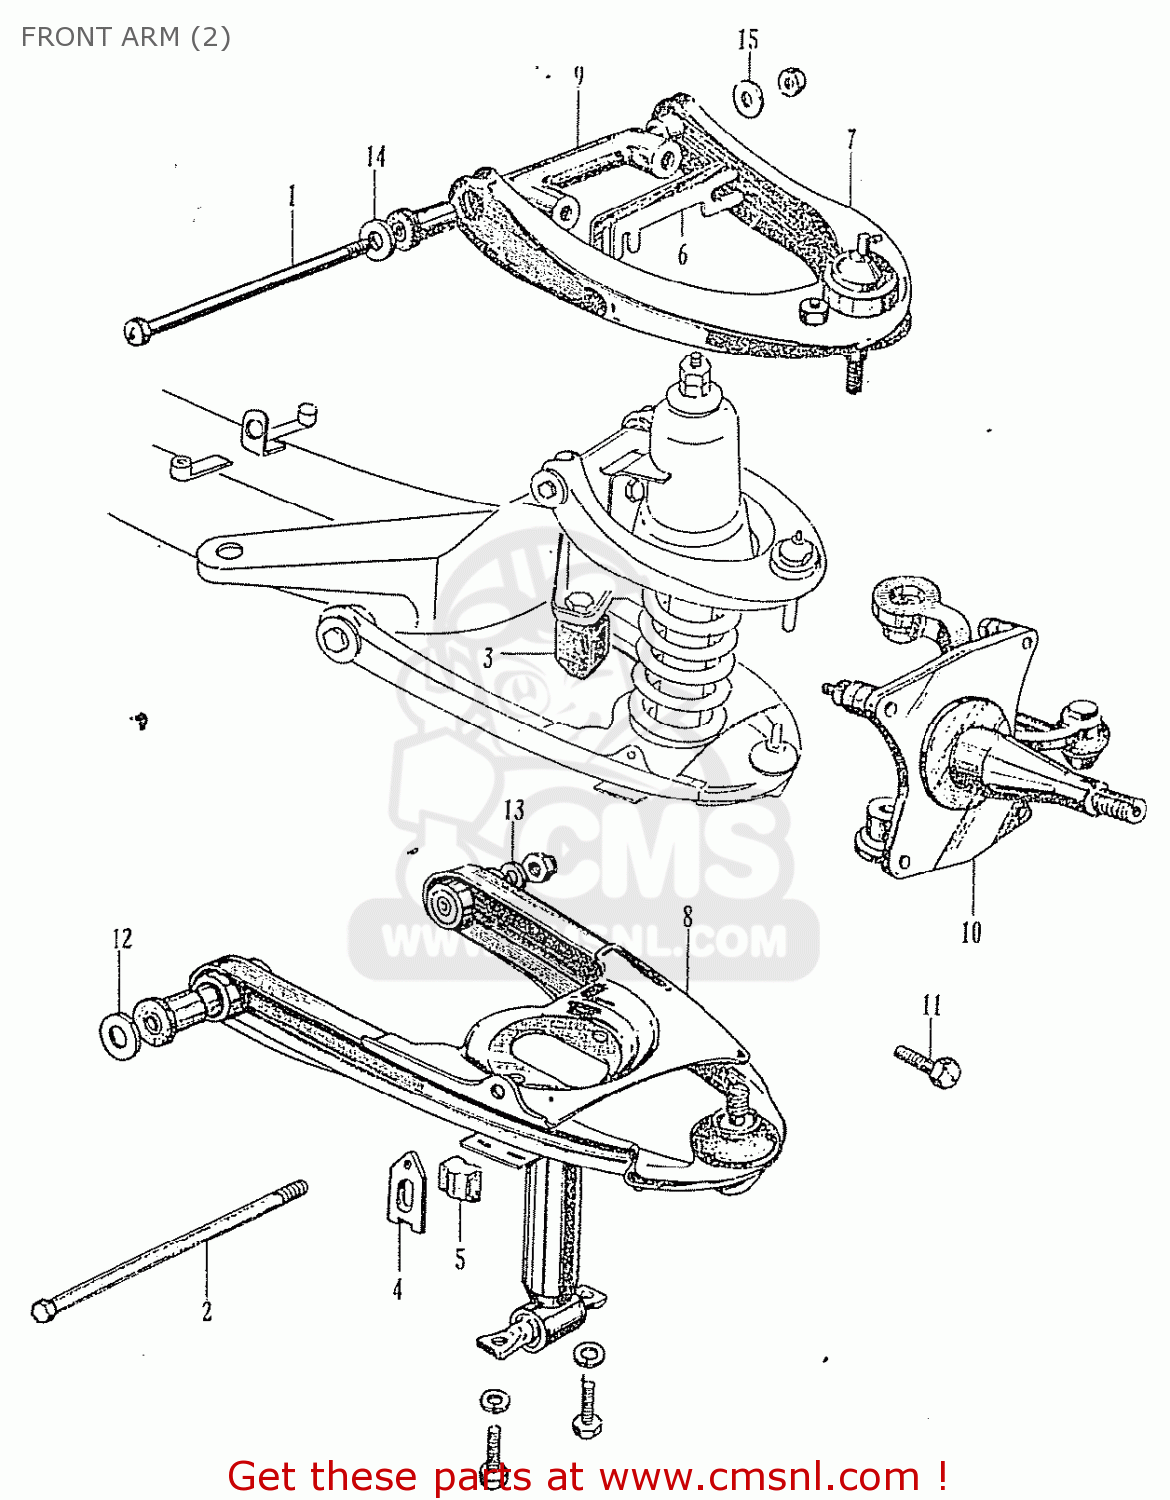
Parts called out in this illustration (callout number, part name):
1	SHAFT, UPPER ARM
2	SHAFT, UPPER ARM
3	STOPPER, FRONT BUMPER
4	PLATE, STABILISER END
5	RUBBER, STABILISER END
6	SHIM, UPPER ARM
7	ARM, LEFT UPPER
8	ARM, LEFT UPPER
9	KNUCKLE, RIGHT
10	KNUCKLE, LEFT
11	BOLT, UPPER ARM
12	WASHER A, SIDE
13	WASHER B SIDE
14	WASHER A, UPPER ARM
15	NIPPLE, GREASE
